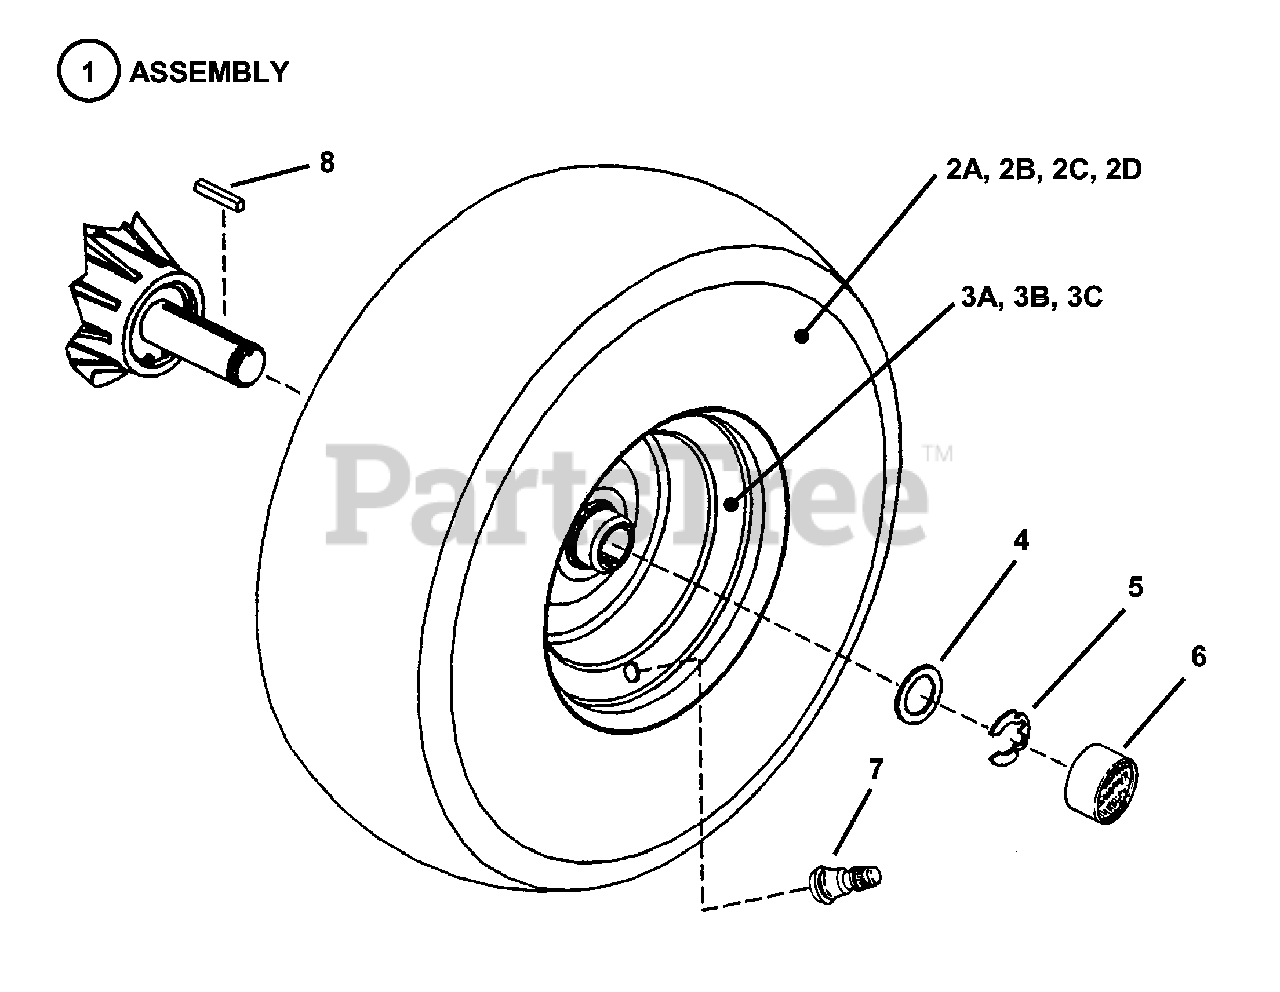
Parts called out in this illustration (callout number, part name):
1	ASSEMBLY, Tire & Rim 18x9.50-8
1	ASSEMBLY, Right Hand AT Tire & Rim 18x8.00-8
1	ASSEMBLY, Left Hand AT Tire & Rim 18x8.00-8
2A	TIRE, 18x9.50-8 Multi-Trac
2B	TIRE, 18x8.00-8 All Terrain Tread
2C	Not Applicable
2D	Not Applicable
3A	RIM, 18 x 8.50
3B	RIM, 18 x 8.00
3C	Not Applicable
4	BUSHING, Machine
5	RING, Retaining, External 1"
6	CAP, Hub
7	STEM, Valve
8	KEY, M6 x 38 Square
